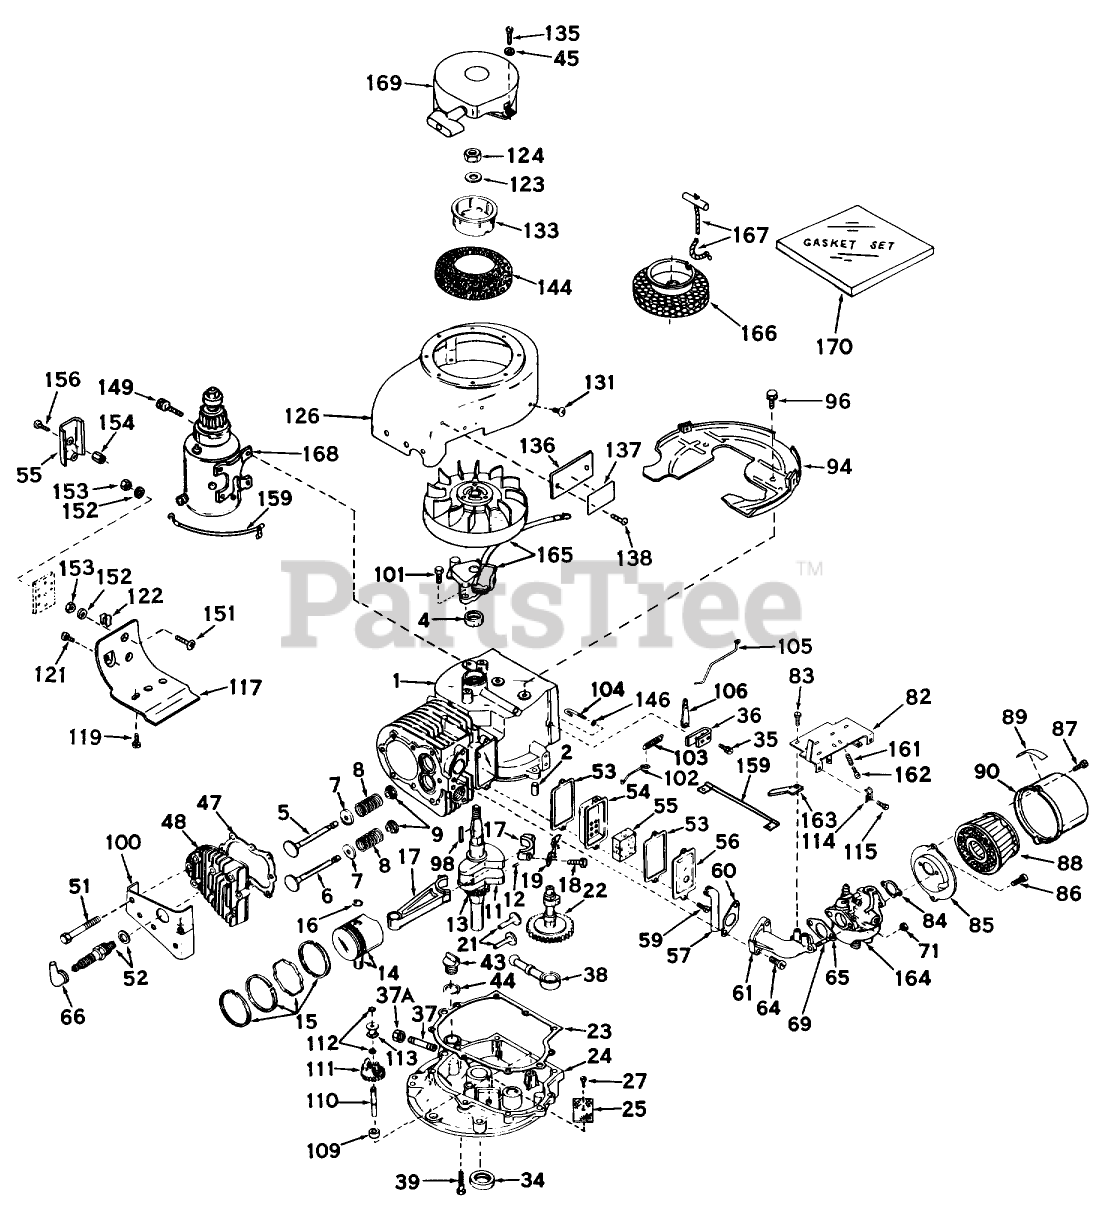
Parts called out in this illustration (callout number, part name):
1	Cylinder Assy. (Incl Nos. 2 4)
2	Pin-Dowel
4	Oil Seal
5	Valve, Intake (Standard)(Incl. No. 9)
5	Valve, Intake (1/32" oversize)(Incl. No. 9)
6	Valve, Exhaust (Standard)(Incl. No. 9)
6	Valve, Exhaust (1/32" oversize)(Incl. No. 9)
7	Cap-Spring, Valve
8	Spring-Valve
9	Keeper-Spring, Valve
11	Crankshaft Assy. (Incl. Nos. 12 13)
12	Pin, Groove
13	Gear-Crankshaft
14	Piston Pin Assy. (Incl. 2 of No. 16)(Standard)
14	Piston Pin Assy. (Incl. 2 of No. 16)(.010 oversize)
14	Piston Pin Assy. (Incl. 2 of No. 16)(.020 oversize)
15	ORing
15	Ring Set (.010" OS)
15	Ring Set (.020" OS)
17	Rod Assy., Connecting (Incl. Nos. 10 18)
18	Screw, Hex Hd.
19	Plate, Lock
21	Lifter Valve
22	Screw
23	Gasket-Cover, Cylinder
24	Flange Assy., Mounting (Incl. Nos. 25, 27, 29, 34, 45 110)
25	Screen-Oil Filter
27	Screw
34	Seal-Oil
35	Screw
36	Clamp-Lever, Governor
37	Nipple, Pipe
37A	Cap-Pipe
38	Pump Assy., Oil
39	Screw (1/4-20 x 1-1/4)
43	Plug-Fill, Oil
44	Gasket
45	Washer
47	Gasket-Cylinder Head
48	CYLINDER HEAD
51	Screw Hex Hd. Cap
52	Plug, Spark (Champion J-8 or equiv.)
53	Gasket-Breather
54	Body-Breather
55	Element-Breather
56	Cover-Valve
57	Tube-Breather
59	Screw
60	Gasket-Intake
61	Pipe-Intake
64	Screw (T-30, 5/16-18x1-3/32)
65	Gasket
66	51005 GIL.ROTARY TI
69	Stud
71	Nut and Lock Washer (1/4-28)
82	Control Assy., Speed (Incl. Nos. 161 162)
83	Screw (10-24 x 9/16)
84	Gasket
85	Bracket
86	Screw (10-32 x 1/2)
87	Screw
88	Element
89	Decal
90	Body
94	Baffle Blower Housing
96	Screw (1/4-20x19/32)
98	Key-Flywheel
100	Cover, Cylinder head
101	Screw
101	Screw, Hex Hd. Cap, Sems
102	Link Governor Spring
103	Spring Governor
104	Rod, Governor (Incl. Nos. 146)
105	Link Governor
106	Lever-Governor
109	Spacer
110	Shaft, Governor
111	Governor Gear ASM
112	Ring-Retaining
113	Spool-Governor
114	Conduit
115	Screw (10-32 x 3/8)
117	Emnsion, Blower Housing
119	Screw
121	Screw
122	51004 GIL ROTARY TI
123	Washer
126	Housing, Blower (Model V70-125148)
126	Housing, Blower (Model V70-125149)
131	Screw, Hex Hd.
133	Cup-Starter
135	Screw
136	IDENTIFICATION PLATE
137	480B GIL SNWTHWR O/
138	DRIVE STUD
144	Screen, Air
146	Washer-Flat
149	Screw
151	56008 ADN.KIT 28727
152	Lockwasher (Model V70-125149)
153	33144C/45C/49A/53A
154	Nut, Long (Model V70-125149)
155	Cover, Panel
156	Screw
159	Wire, Ground
161	Spring-Compression
162	Screw
163	Clip
164	Carburetor
165	Magneto
165	Magneto, Alternator (Model V70-125149)
166	Hub Screen, Rope Starter
167	Rope Assy., Starter
168	Motor, Starter
169	Starter, Rewind
170	Gasket Set
